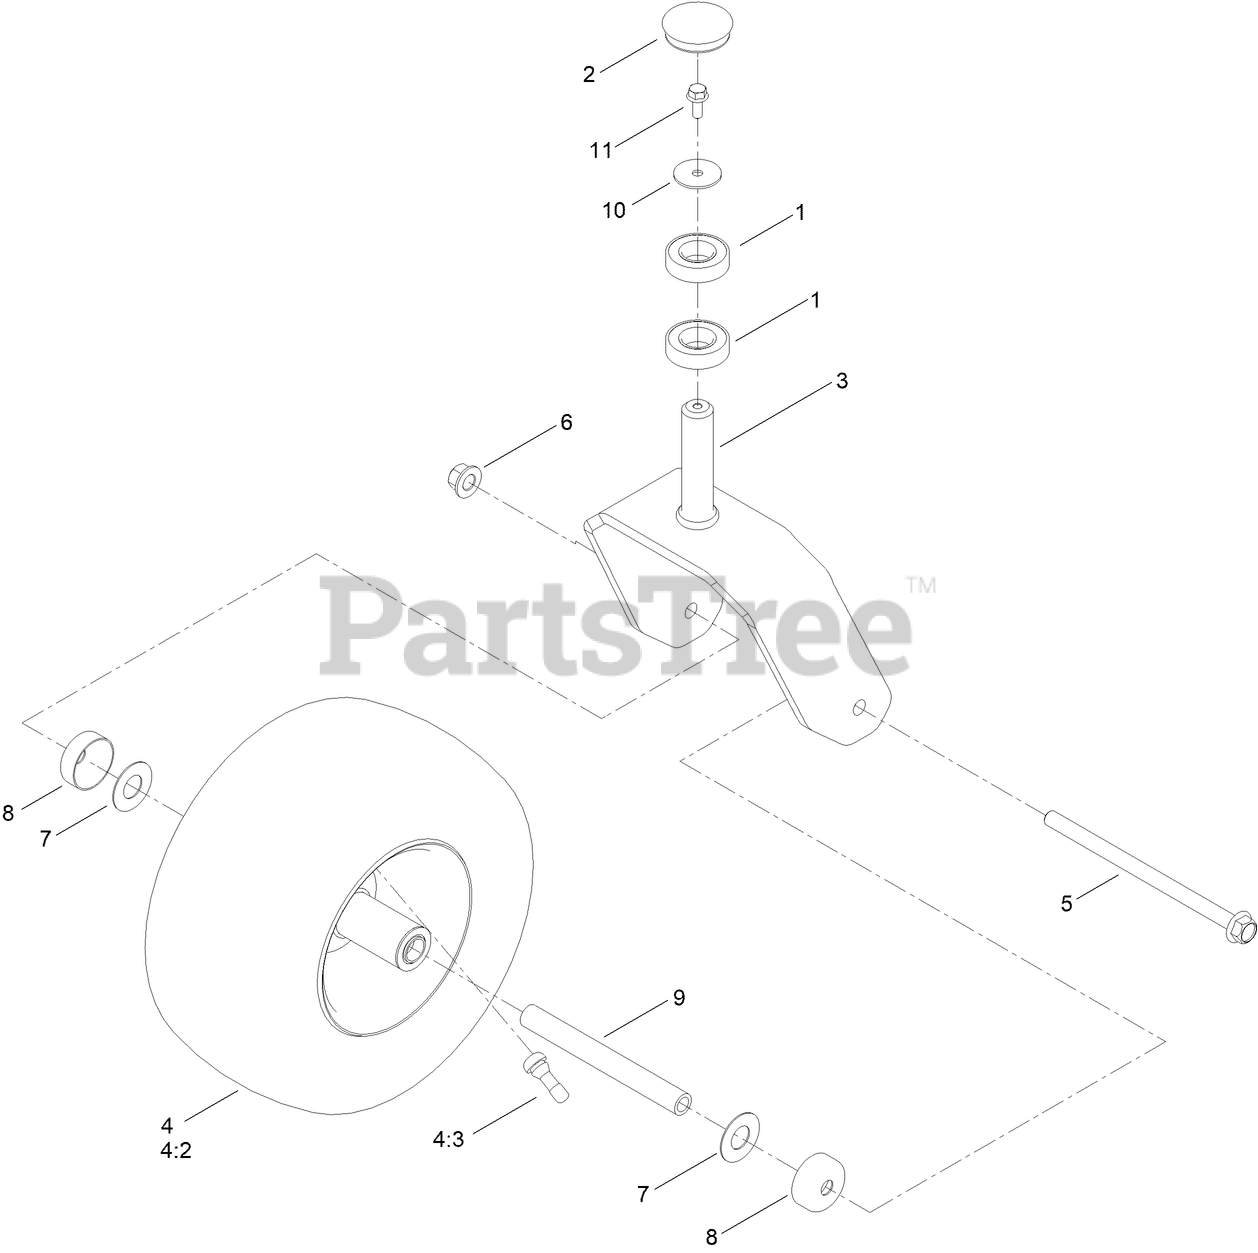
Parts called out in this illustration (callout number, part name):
1	BEARING-BALL
2	CAP,GREASE
3	FORK ASM
4	CASTER TIRE ASM 13X6.5-6
4:2	TIRE 13X6.5-6
5	SCREW-HHF
6	NUT-LOCK
7	WASHER
8	GUARD-SEAL
9	SPANNER-WHEEL
10	WASHER-FLAT
11	SCREW-HHF
